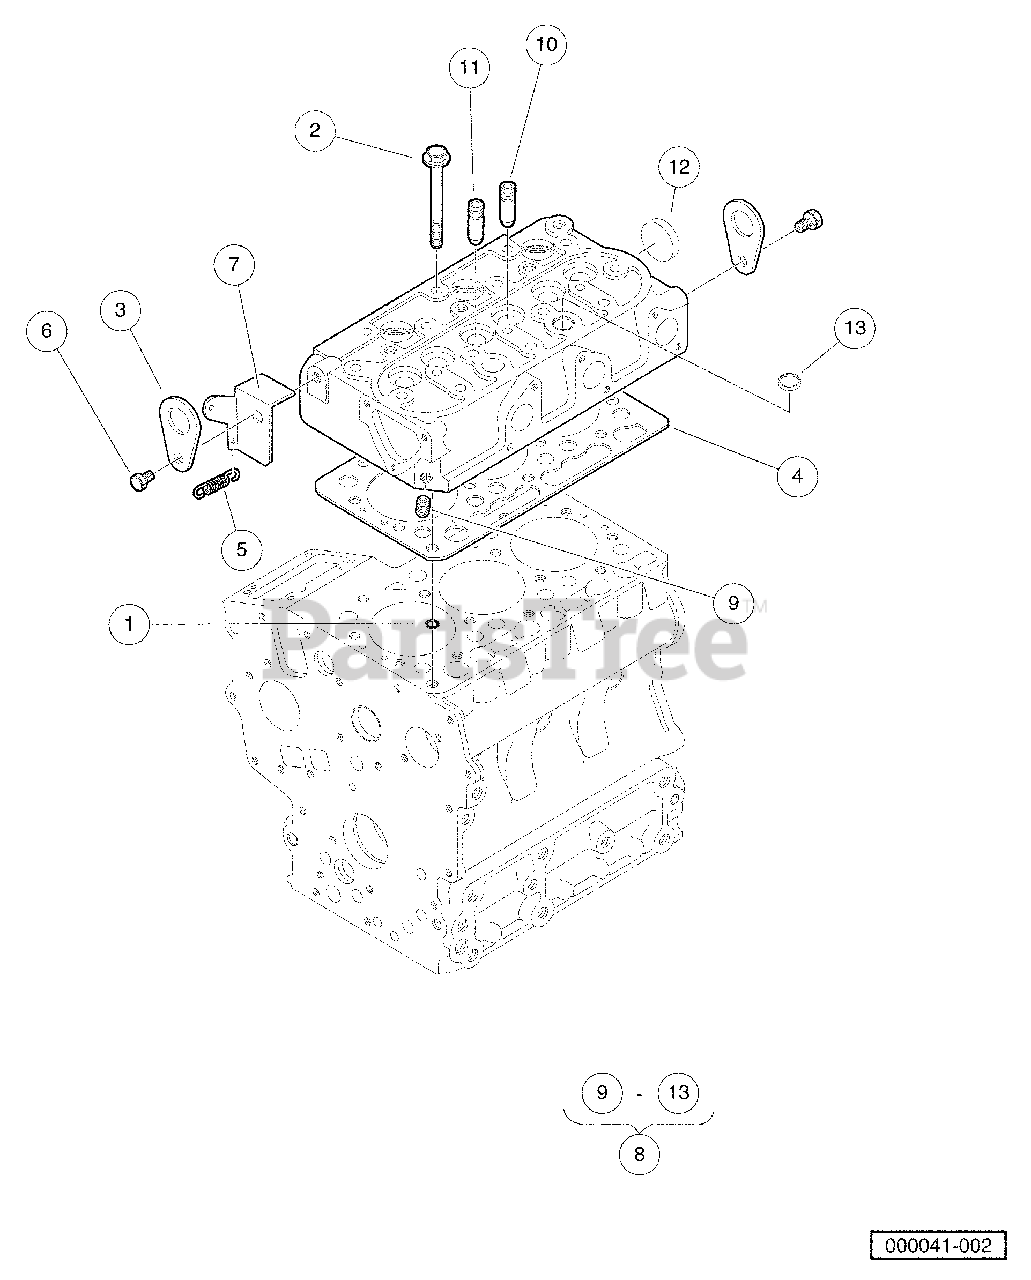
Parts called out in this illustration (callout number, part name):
1	O Ring, 8 X 7
2	Bolt, Cylinder Head
3	Hook, Engine.
4	Gasket, Cylinder Head
5	Spring, Start
6	Bolt, Engine Hook
7	Stay, Cylinder Head
8	Head, Cylinder, Complete
9	Plug, 3/32"
10	Guide, Exhaust Valve.
11	Guide, Inlet Valve
12	Cap, Sealing, Head
13	Cap, Sealing, Head, Top.
